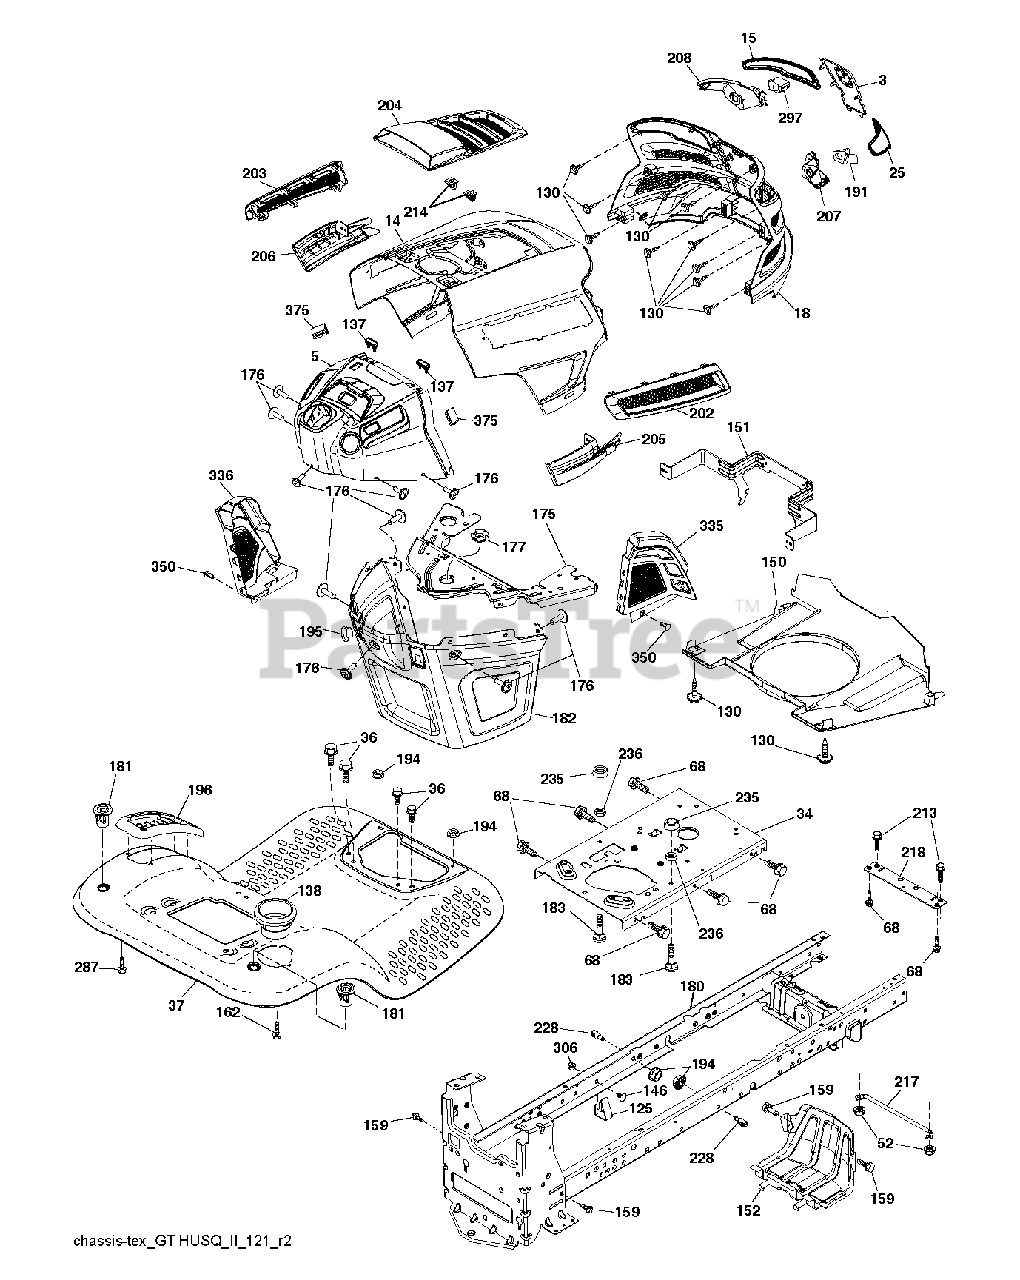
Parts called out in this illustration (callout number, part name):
3	APPLIQUE.SUBASM.GT.HUSQ.II
5	DASH.UPR.ASSY.GT2.SRV.MIND.MAN
14	HOOD.ASM.HUSQVARNA.GT.TEX.ORAN
15	LENS.HEADLIGHT.LH.GTII.2011
18	GRILLE.SUBSTRATE.2011.
25	LENS.HEADLIGHT.RH.GTII.2011
34	PLATE.ENGINE.WELDED.CHASSIS
36	SCREW 5/16"
37	FENDER.TLT.PDL.CNTRL.W/CPH.ORG
52	LOCKNUT
68	SCREW LT
125	CLIP.FUEL.LINE
130	SCREW.#10 X 0.750.BOS
137	BUMPER DASH
138	HOLDER.CUP.LT.GREY
146	BOLT.RDHD.SHT.SQNK.3/8-16X5/8
150	AIR DUCT.GTV2(1.66"RING HEIGHT
151	BRACKET.PIVOT.HOOD.GT.HUSQ.II
152	SHIELD.BROWNING.PNT.GT.V2
159	SCREW, 3/8-16X3/4
162	SCREW.HI-LO.CONSOLE
175	PLATE.CROSSMEMBER.HUSQ
176	SCREW.#10-24X5/8.RN.QU
177	BUSHING STEERING
180	CHASSIS
181	BUSHING.MNT.FEND.CRGO.TEX.49
182	DASH.LOWER.COMMON.12V.ADAPTOR
183	BOLT.5/16-18X1-1/4 FULL THD
191	INSERT.REFLECTIVE.RH.HUSQ.GTII
194	NUT LOCK HEX FLANGE 5/16-18
195	PLUG.HOLE.DASH.LOWER.12V.BLK
196	DECKLFT.CONSOL FULL ASSM GREY
202	VENT.SIDE.RH.GT.HUSQ.II.
203	VENT.SIDE.LH.GT.HUSQ.II.498
204	VENT.TOP.ASM.HUSQ.GT2
205	SIDE.TRIM.RH.GT.HUSQ.II
206	SIDE.TRIM.LH.GT.HUSQ.II.GRAY
207	BEZEL LIGHT.RH.GT.II.MYLAR
208	BEZEL LIGHT.LH.GT.II.MYLAR
213	BOLT
214	CLIP.RETAINER.TINNER.
217	ROD.PIVOT.HOOD
218	X-PIECE.HOOD.STOP.NON/
228	STUD.FASTNER.W/ANTI-ROTATE
235	SPACER FENDER
236	NUT.CENTERLOCK.5/16-
287	SCREW 1/4X20
297	INSERT.REFLECTIVE.LH.HUSQ.GTII
306	NUT LOCK FLG 3/8-16 UNC
335	COVER.LOWER.DASH.RH.BLACK
336	COVER-LH.LOWER.DASH.GT2.BLACK
350	CLIP.X-MAS.TREE
375	BUMPER CLIP-ON. DASH 1"
